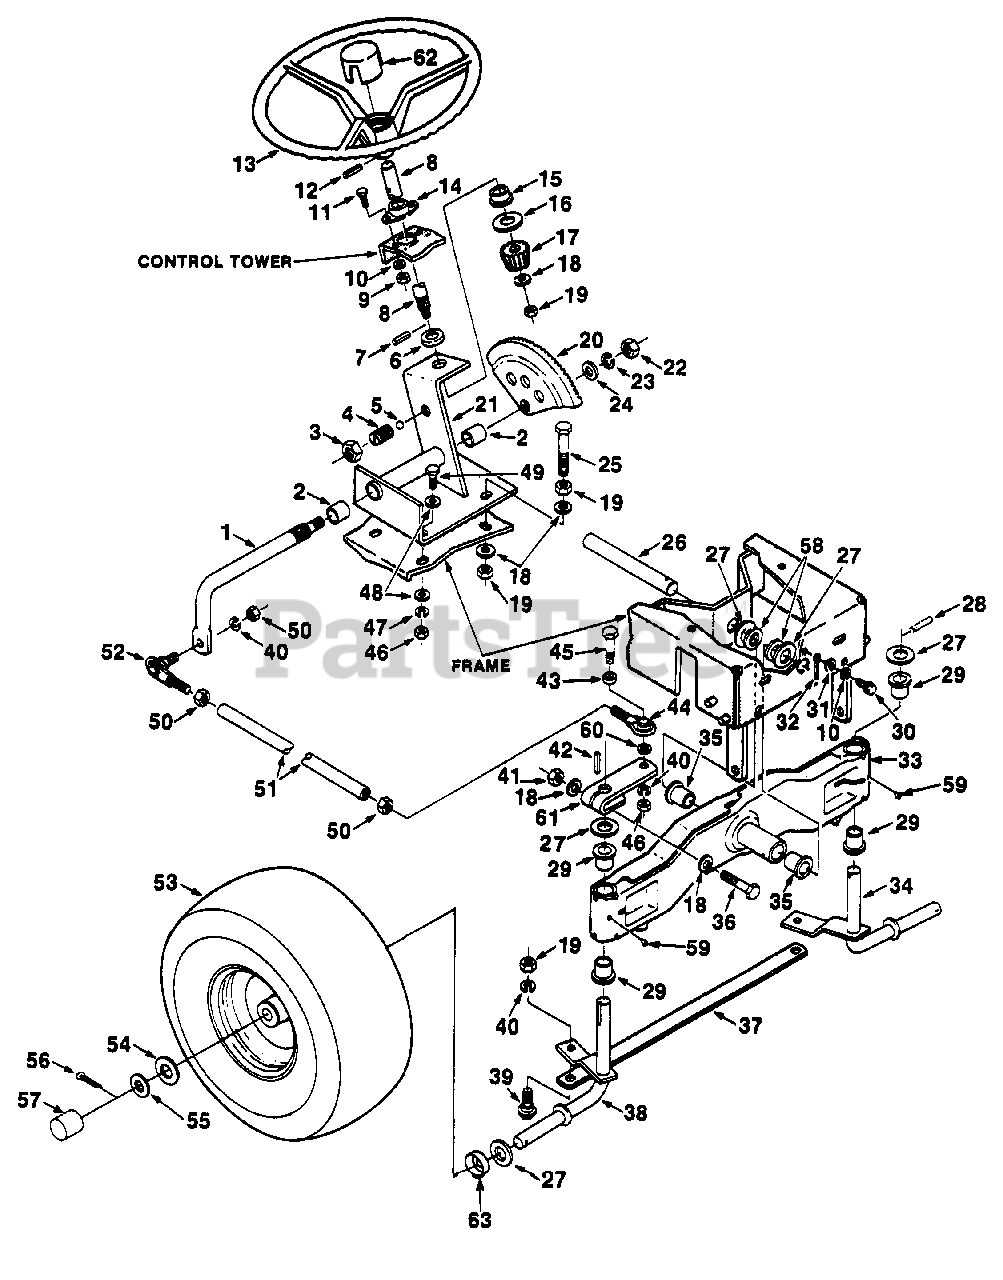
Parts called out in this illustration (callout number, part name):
1	ARM- Pitman
4	SPACER- Bearing
5	BALL-.312 dia.
6	SPACER- Steering
7	PIN- Roll 3/16 x 1
8	SHAFT- Steering wheel
9	NUT- Hex 1/4-26
10	WASHER- Lock 1/4
11	SCREW- Hex 1/4-20 x 1/2
12	PIN- Roll 1/4-1
13	WHEEL- Steering
14	BEARING- Steering shaft
17	PINION- Steering
19	NUT- Hex 3/8-16
20	STEERING- Gear
21	SUPPORT- Steering
22	NUT- Hex 1/2-13
23	WASHER- Lock 1/2
24	WASHER- Flat 1/2
25	SCREW- Hex 3/8-16 x 2
27	WASHER- Flat 3/4
28	PIN- Roll 1/4 x 1 1/2
29	BUSHING- Spindle
30	SCREW- 1/4-20 x 3/4
31	WASHER- Plain 1/4
32	PIN- Cotter
33	FRONT AXLE ASSY.
36	SCREW- Hex 3/8-16 x 2 1/4
38	SPINDLE- R.H.
39	BOLT- Tie bar mounting
40	WASHER- 3/8 lock
41	NUT- Centerlock 3/8-16
42	KEY- 3/16 x 1 1/2
43	SPACER- Bell joint
44	BALL JOINT
45	SCREW- Hex 3/8 x 16 x 1 3/4
46	NUT- Hex 5/16-18
47	WASHER- Lock 5/16
48	WASHER- 5/16
49	SCREW- Hex 5/16-18 x 7/8
50	NUT- Hex 3/8-24
52	BALL JOINT
53	RIM & TIRE ASSY.
55	WASHER-HT
56	PIN- Cotter 5/32 x 1 1/4
59	FITTING- Grease
60	SPACER- Ball joint
61	ARM- Steering
62	CAP- Steering wheel
63	WASHER- Dust
